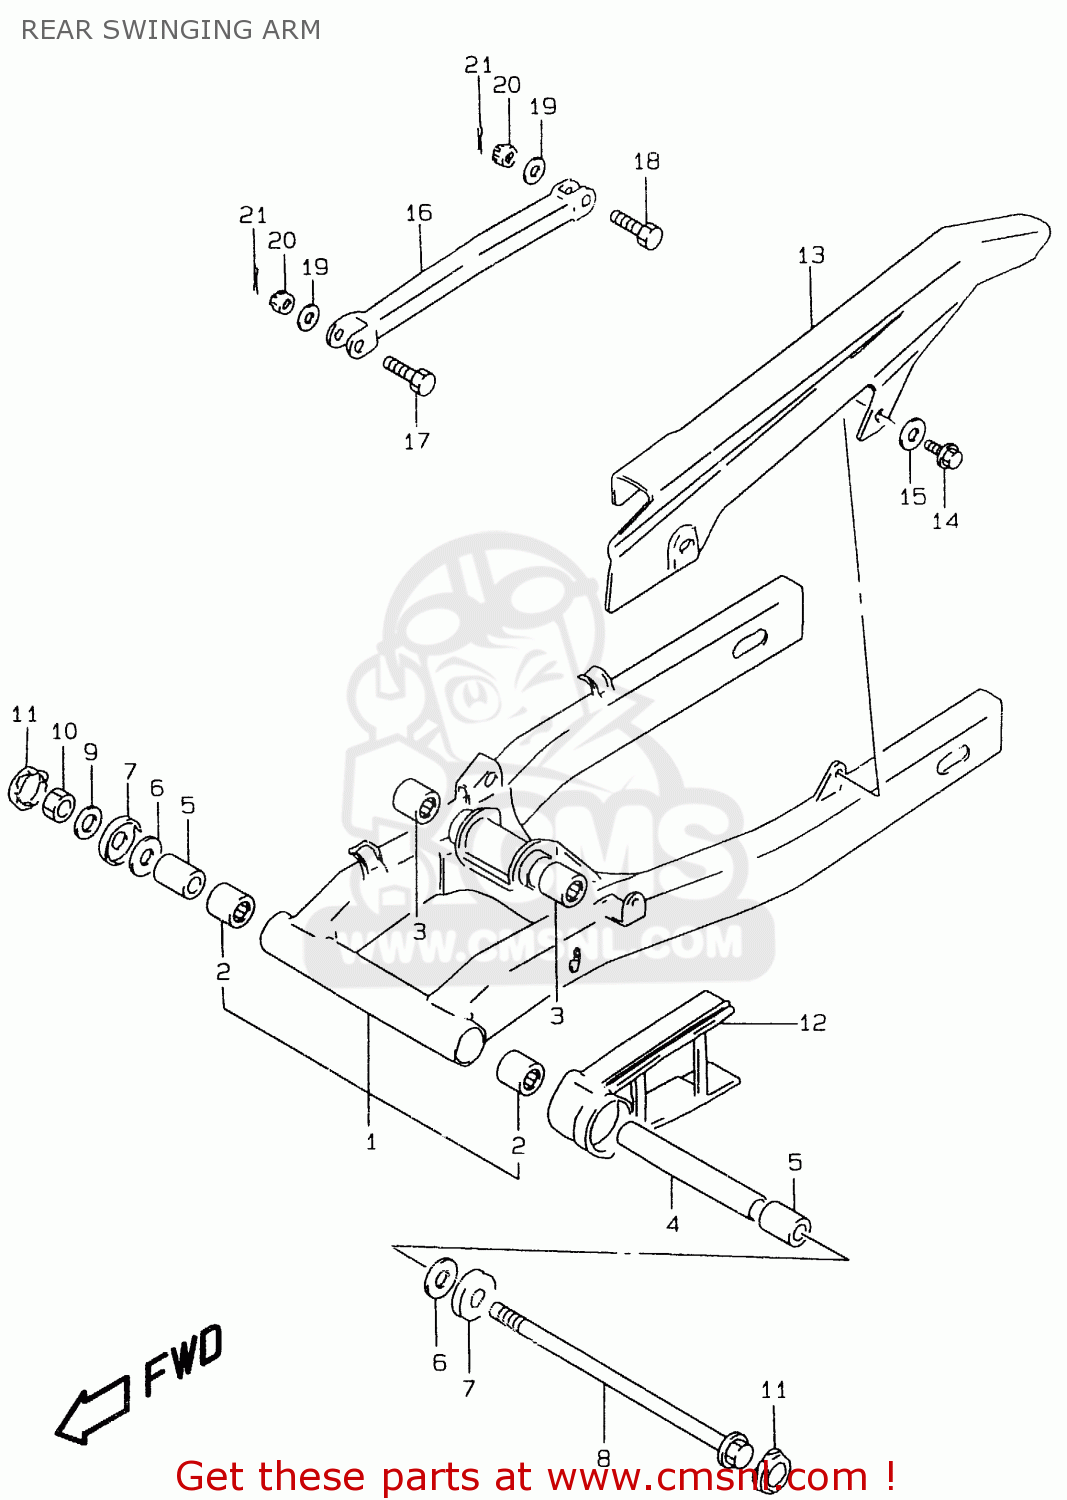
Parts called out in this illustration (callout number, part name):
1	SWINGINGARM ASSY,RR
2	BEARING(22X29X30)
3	BEARING(17X24X25)
4	SPACER,RR SWGARM PIVOT CTR
5	SPACER,RR SWGARM PIVOT
6	WASHER(14.2X34X1)
7	CVR,RR SWGARM DUST SEAL(OD:40)
8	SHAFT,RR SWINGINGARM PIVOT
9	WASHER(14.5X29X2.3)
10	NUT
11	CAP,RR SWINGING ARM PIVOT
12	BUFFER,CHAIN TOUCH DEFENSE
13	CASE,CHAIN
14	SCREW 6X12
15	WASHER
16	TORQUELINK,RR
17	BOLT(10X41)
18	BOLT(10X35)
19	WASHER(10.5X20X3.2)
20	NUT
21	PIN 20X20
